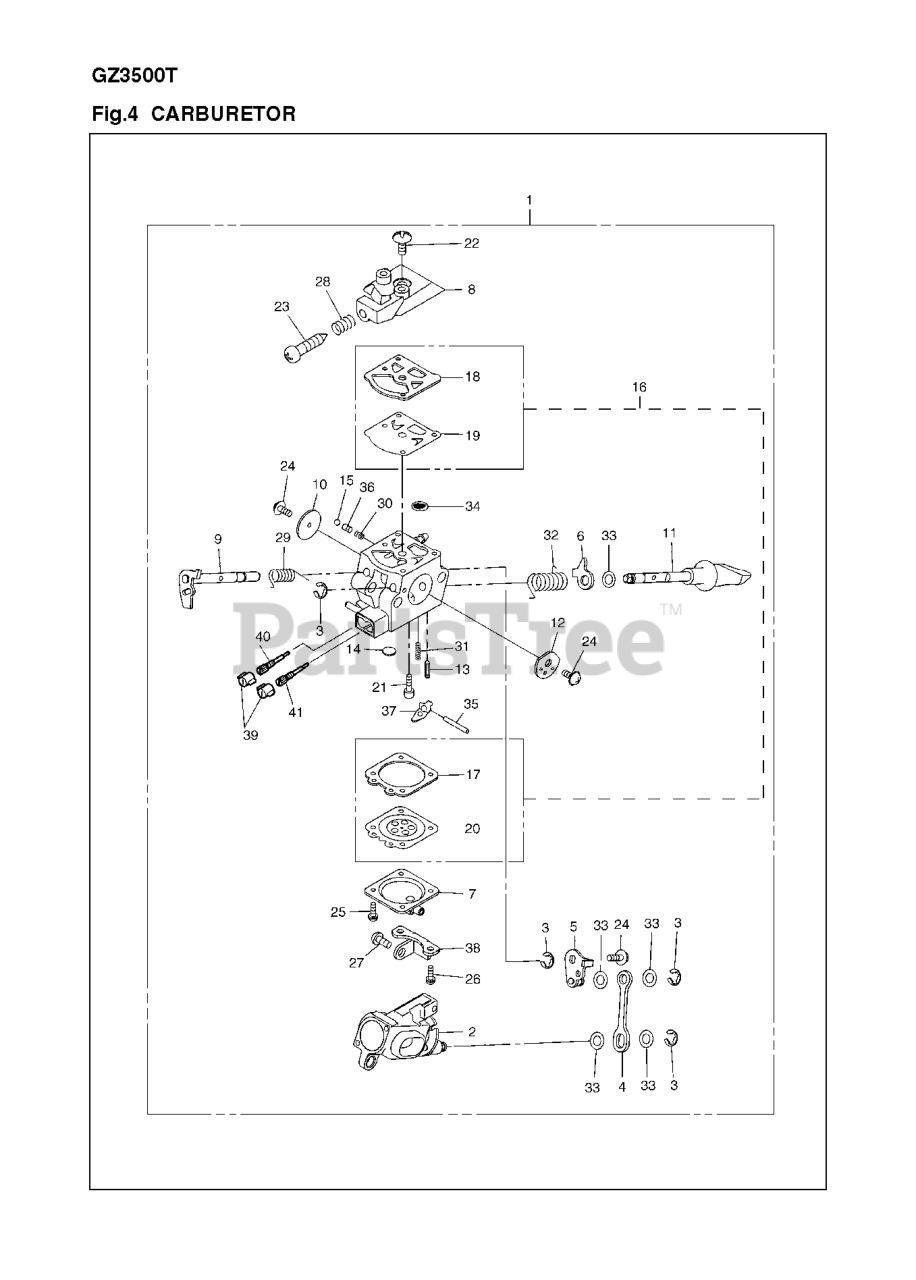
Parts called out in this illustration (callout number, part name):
1	CARBURETOR ASSY
2	BODY ASSY AIR V
4	ROD, LINK
5	LINK ASSY THROT
9	SHAFT ASST THRO
11	SHAFT ASSY CHOKE
12	CHOKE VALVE
13	VALVE INLET
15	BALL
16	GASKET, KIT
17	GASKET
18	GASKET
19	DIAPHRAGM
20	DIAPHRAGM
24	SCREW
25	SCREW ASSY
26	SCREW ASSY
29	SPRING RETURN
30	SPRING
31	SPRING
34	SCREEN
36	PISTON
39	CAP
